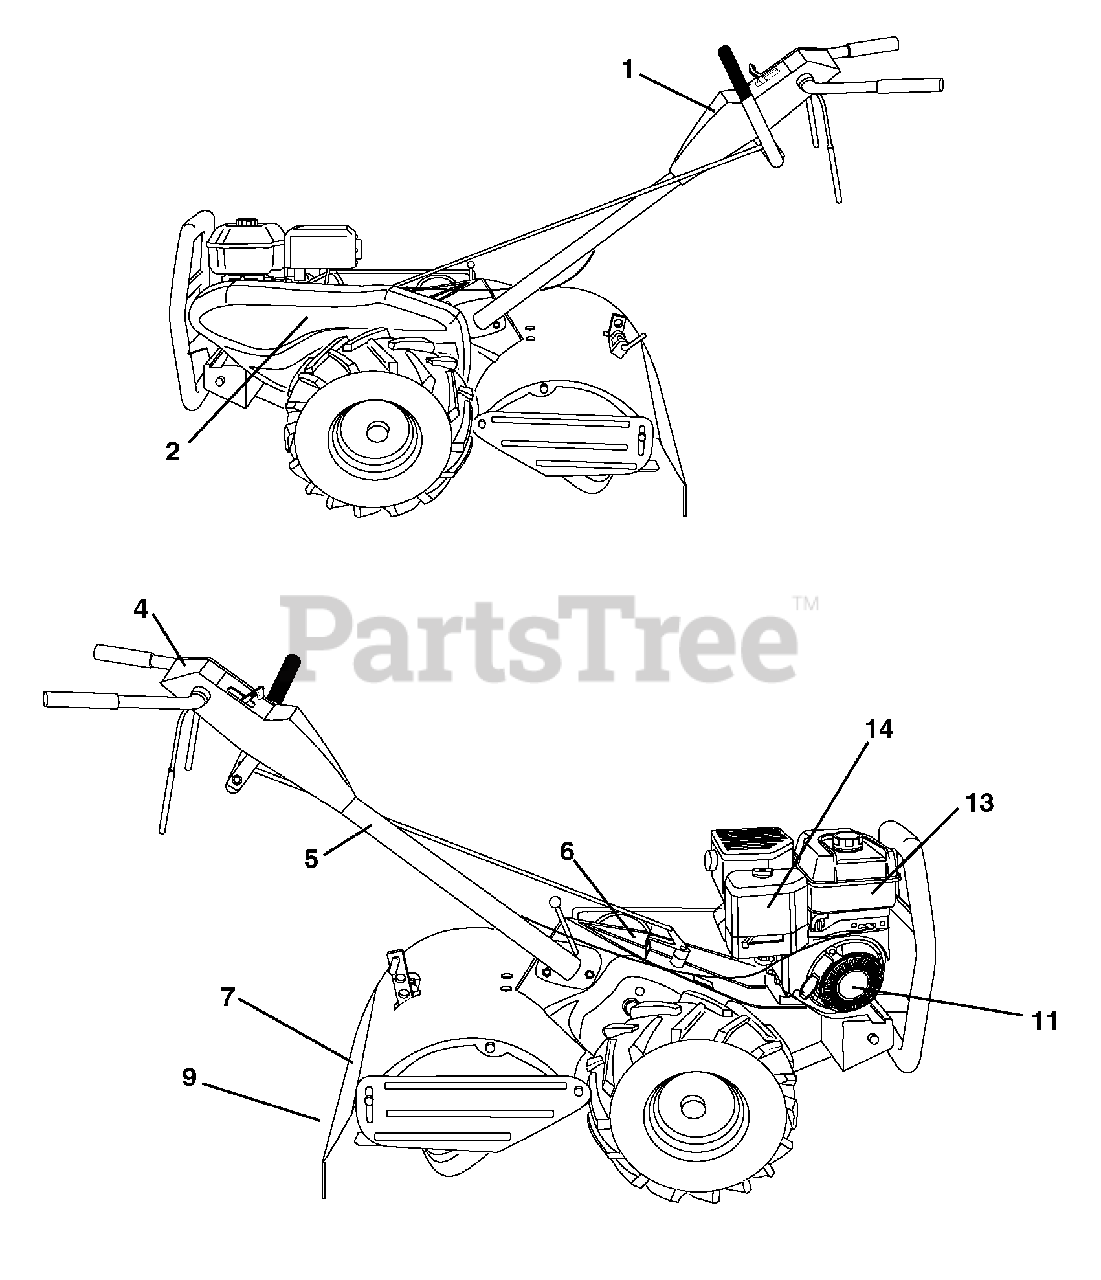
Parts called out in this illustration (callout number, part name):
1	Decal, CNTRL PNL
2	Decal, Decal, Blt Grd
4	Decal, Instruction, Tilling
5	Decal, Hand Placement
6	Decal, Shift Indicator
7	Decal, caution
9	Decal, Warning, Rotating Tines
11	Decal, Rewind
13	Decal, B&S Tank
14	Decal, B&S Air Cleaner
14	Manual, Operator's (E&F)
14	Manual, Parts (E&F)
